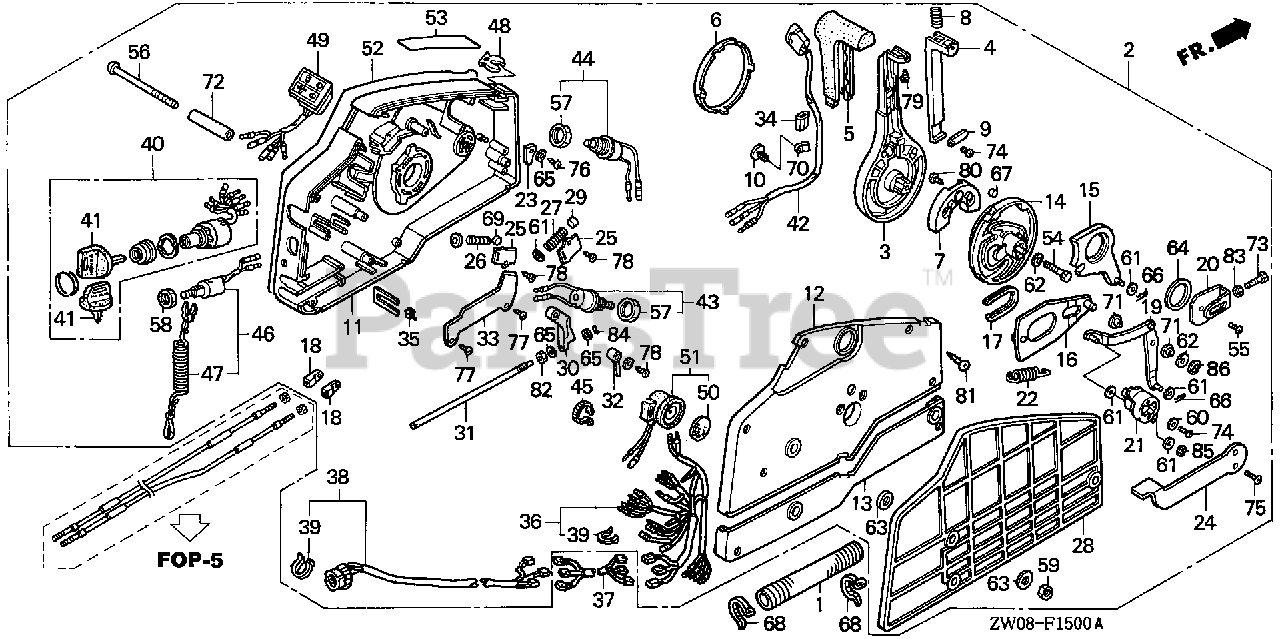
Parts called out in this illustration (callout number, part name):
1	TUBE, CORRUGATED (28MM)
2	BOX ASSY., REMOTE CONTROL
3	HANDLE, REMOTE CONTROL
4	LEVER, HANDLE LOCK
5	GRIP, REMOTE CONTROL HANDLE
6	CAP, HANDLE
7	BLOCK, NEUTRAL LOCK
8	SPRING, REMOTE CONTROL HANDLE
9	PLATE, LEVER SETTING
10	CLAMP, HARNESS
11	HOUSING, REMOTE CONTROL BOX (A)
12	HOUSING, REMOTE CONTROL BOX (B)
13	HOUSING, REMOTE CONTROL BOX (C )
14	WHEEL, CONTROL
15	ARM, SHIFT LINK
16	PLATE, SLIDING
17	COLLAR, SLIDING PLATE
18	PIVOT, SHIFT
19	ARM, LINK JOINT
20	BRACKET, LINK JOINT
21	WHEEL, ACCELERATOR
22	SPRING, ACCELERATOR WHEEL
23	CAM, STARTER SWITCH
24	LEVER, IDLE
25	PLATE, SPRING SETTING
26	SPRING, SHIFT CLICK
27	SPRING, CHOKE RETURN
28	SPACER, REMOTE CONTROL BOX
29	SPACER, CLICK SPRING
30	BLOCK, THROTTLE FRICTION
31	BOLT, FRICTION
32	SPACER, NEUTRAL SWITCH
33	CLAMP, POWER TILT CORD
34	PIPE, HARNESS GUIDE
35	SPACER, CABLE CLAMP
36	CABLE ASSY., REMOTE CONTROL (B) Use from Frame SN 1300029.
37	CABLE ASSY., REMOTE CONTROL EXTENSION Use from Frame SN 1300029.
38	CABLE ASSY., SWITCH PANEL
38	CABLE ASSY., SWITCH PANEL Use from Frame SN 1300360.
39	TIE, CABLE (NATURAL 2.4X92) Use up to Frame SN 1300359.
40	SWITCH ASSY., COMBINATION DUAL QTY = (2) (SINGLE)
41	KEY ASSY., COMBINATION SWITCH (35100-ZV5-003 ONLY) DUAL QTY = (4) (SINGLE)
42	SWITCH ASSY., POWER TRIM-TILT
44	SWITCH ASSY., SOLENOID
45	BAND (BLACK 3.5X140)
46	SWITCH ASSY., EMERGENCY STOP
47	WIRE, EMERGENCY (SINGLE) (DUAL)
48	CLIP, EMERGENCY LOCK
49	LAMP ASSY., INDICATION (2-LED)
50	PLATE, TURN SIGNAL BUZZER DUAL QTY = (2) (SINGLE)
51	BUZZER, WARNING DUAL QTY = (2) (SINGLE)
52	PLATE, REMOTE CONTROL (CAUTION=SILVER)
53	MARK, FAST IDLE
54	BOLT, HEX. (8X35) Use up to Frame SN 4800712.
55	SCREW, PAN (6X10)
56	SCREW (6X95)
57	NUT, HEX. (20MM) Use up to Frame SN 1300359.
58	NUT, HEX. (16MM) DUAL QTY = (2) (SINGLE)
59	NUT, HEX. (6MM)
60	WASHER, PLAIN (5MM)
61	WASHER, PLAIN (6MM) Use up to Frame SN 4800342.
62	WASHER, PLAIN (8MM) Use up to Frame SN 4800712.
63	WASHER (6MM)
64	WASHER (28MM)
65	WASHER, PLAIN (4MM) Use up to Frame SN 4800712.
66	PIN, LOCK (6MM)
67	PIN (6X6)
68	BAND, SELF-LOCK Use from Frame SN 3000253.
69	ROLLER, CLICK
70	CLIP, WIRE HARNESS (6.3MM)
71	COLLAR, LINK JOINT
72	COLLAR, DISTANCE (6X10X43.5)
73	BOLT, HEX. (5X16)
74	SCREW, PAN (5X10)
75	SCREW, OVAL (5X12) Use up to Frame SN 4800712.
76	SCREW, TAPPING (4X10)
77	SCREW, TAPPING (5X8) (FOR SILVER MUFFLER)
78	SCREW, TAPPING (5X10)
79	SCREW, TAPPING (5X12)
80	SCREW, TAPPING (6X16)
81	SCREW, TAPPING (5X25)
82	NUT, HEX. (6MM)
83	NUT, HEX. (5MM)
84	E-RING (3MM)
85	E-RING (4MM)
86	E-RING (7MM)
